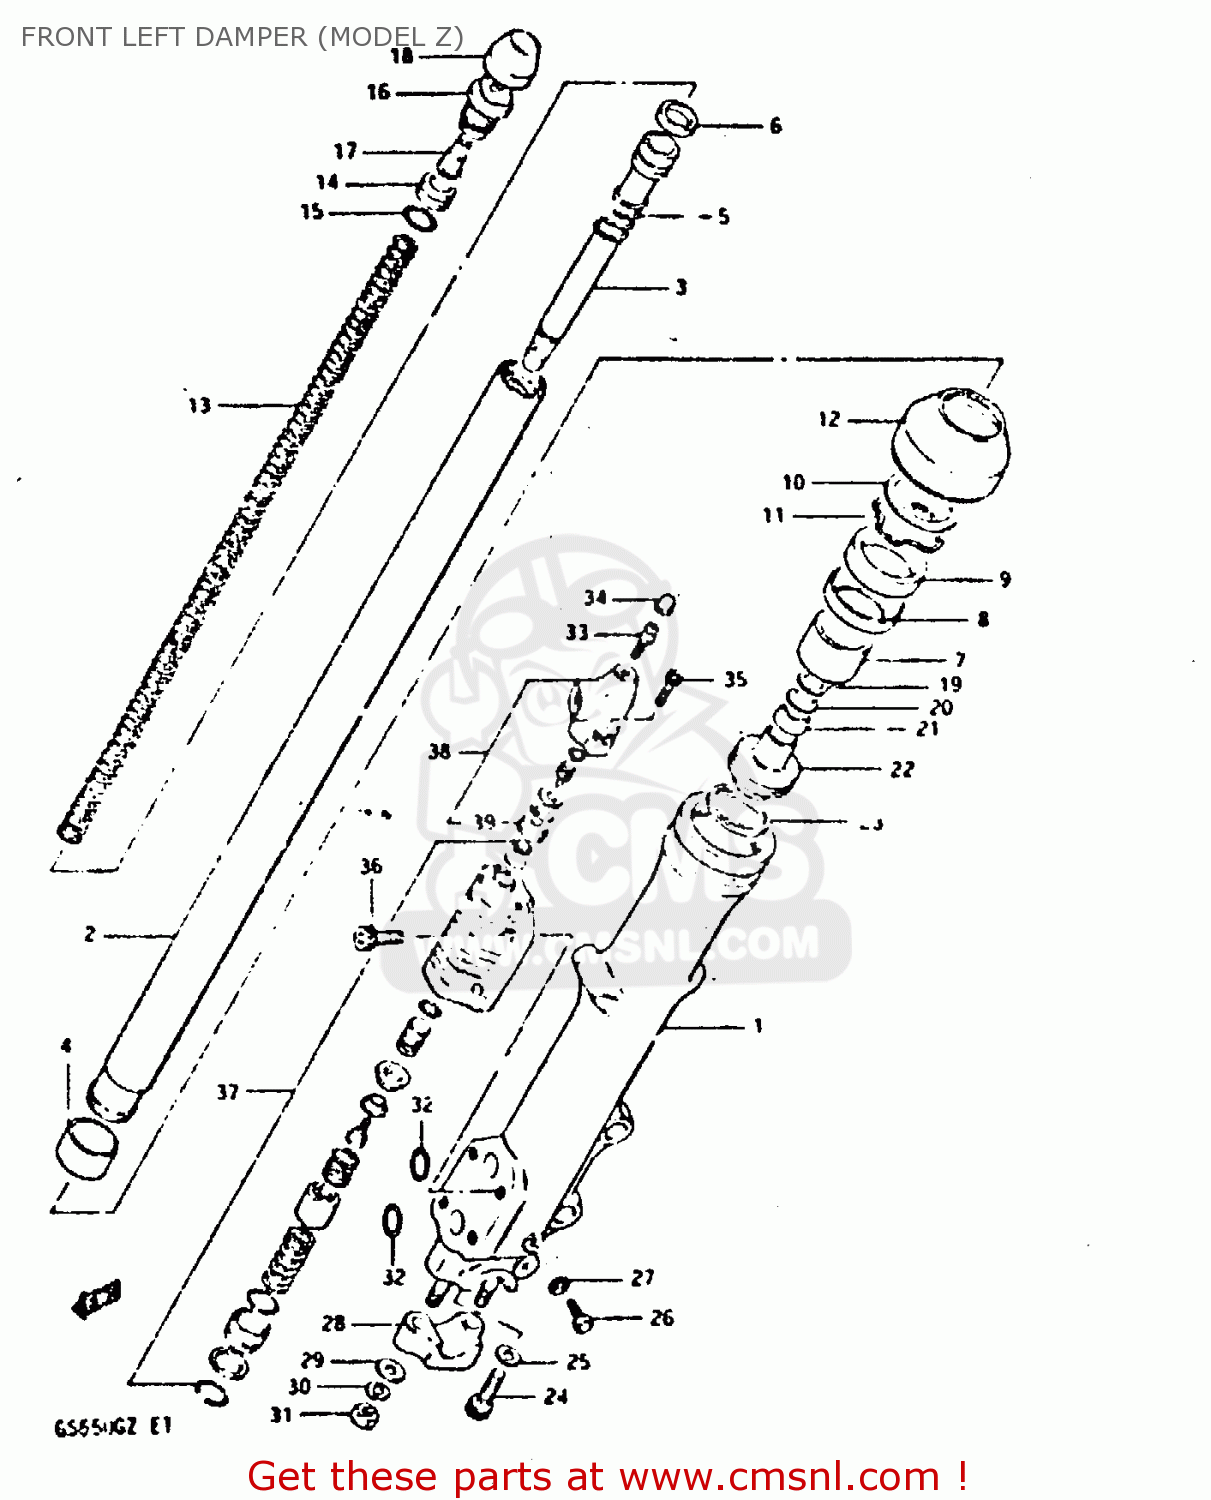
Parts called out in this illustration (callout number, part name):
1	TUBE,OUTER,LEFT
2	INNER TUBE
3	CYLINDER
4	PISTON
5	SPRING,FORK REBOUND
6	RING,PISTON
7	GUIDE,FORK INNER TUBE
8	SPACER,SEAL
9	OIL SEAL,FRONT FORK
10	RING,BACKUP
11	CIRCLIP,INNTERNAL
12	DUST SEAL
13	SPRING
14	SEAT,FRONT FORK SPRING
15	O RING
16	CAP,FORK INNER TUBE
17	ADJUSTER,SPRING
18	CAP
19	VALVE
20	SPRING,VALVE
21	VALVE,OIL LOCK PIEACE
22	PIECE,OIL LOCK
23	RING,PISTON
24	BOLT(8X27)
25	GASKET (NAS)
26	BOLT
27	GASKET,DRAIN,PLUG (NAS)
28	HOLDER,AXLE
29	WASHER
30	LOCK WASHER
31	NUT
32	O RING,FR FORK
33	BREATHER
34	CAP
35	BOLT
36	BOLT
37	MODULATOR VALVE SET,FRONT
38	MODULATOR PARTS SET,FRONT
39	SEPARATOR,FRONT FORK MODULATOR
